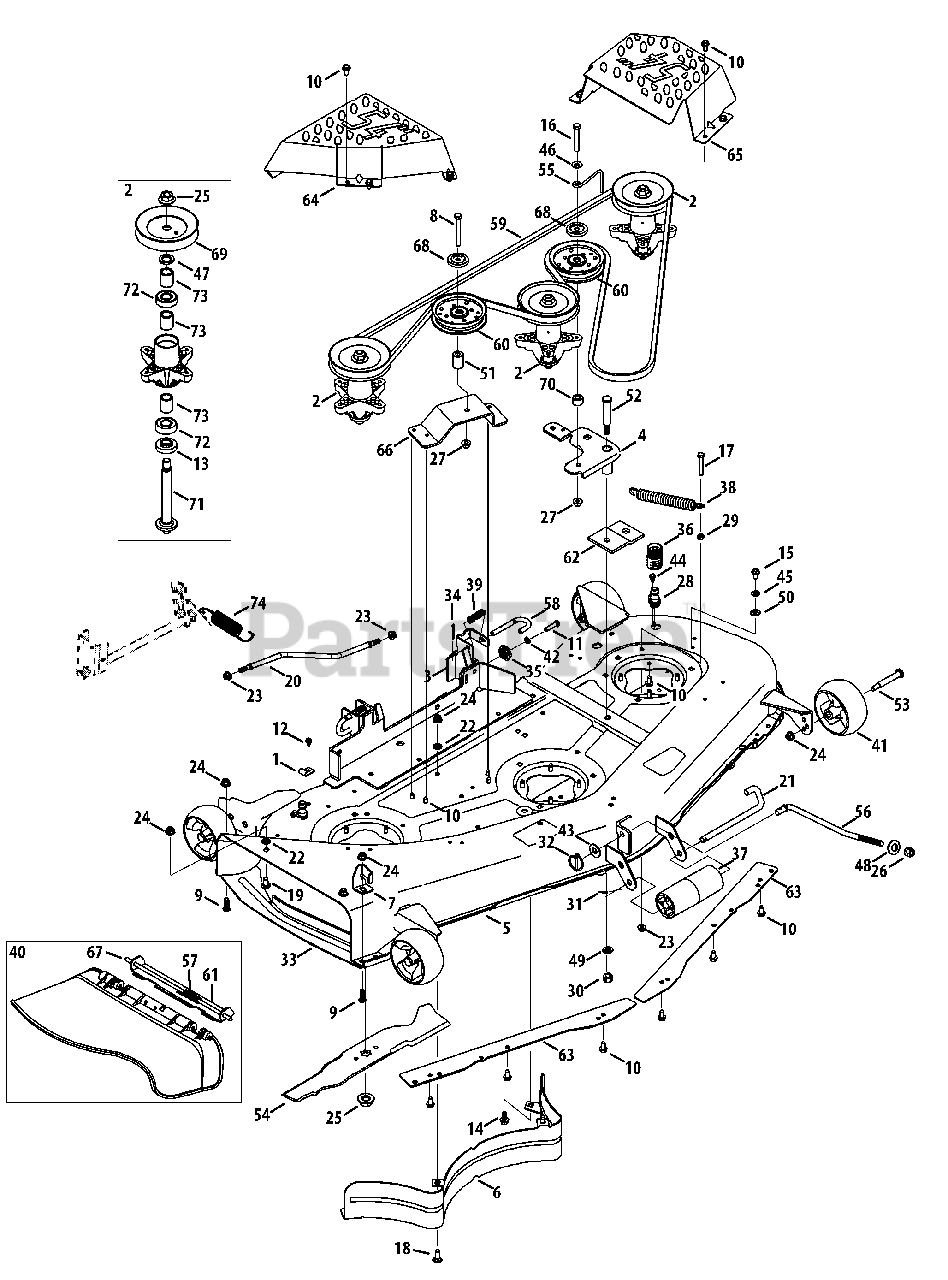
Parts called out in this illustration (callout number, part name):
1	Bracket, Hook, Retainer
2	Spindle Assembly
3	Bracket Assembly, Deck, Hanger LH
4	Idler Assembly, Arm, 54"
5	Deck Assembly, 54"
7	Stop, Chute, Deflector
8	Hex Screw, 3/8-16, 3.0, Gr8
9	Hex Screw, 3/8-16, 1.00, Gr5, Spec
10	Screw, Self-tapping, 5/16-18, .750,
11	Hex Screw, 5/16-18, 1.25, Gr5, Std
12	Screw, Self-tapping, 1/4-20, 0.500
13	Spacer, .79 x 1.82 x .55lg.
14	Screw, Self-tapping, 3/8-16, 0.750
15	Screw, Self-tapping, 5/16-18, 0.875
16	Hex Screw, 3/8-16, 2.50, Gr5, Std
17	Hex Screw, 5/16-18, 2.00, Gr5, Std
18	Bolt, Carriage, 3/8-16, 1.00, Gr5
19	Bolt, Carriage, 3/8-16, 0.75, Gr1
20	Rod, Support, Deck
21	Roller Pin-1/2 Dia. x 7.31
22	Nut, Push, 3/8
23	Nut, Flange Lock, 5/16-18, Nylon
24	Nut, Flange Lock, 3/8-16, Nylon
25	Nut, Flange, 5/8-18
26	Nut, 1/2-13
27	Nut, Flange Lock, 3/8-16, GrF
28	Deck Wash Nozzle
29	Nut, Hex, 5/16-18, Gr5
30	Nut, Hex Lock, 1/2-13, GrB
31	Pin, Cotter, 3/32, 1.0
32	Pin, Lynch, .1875
34	Pin, Cotter, 1/8 x 1.25
35	Gear, Deck, Adjustment
36	Coupler, Water
37	Roller, Front
38	Spring, Extension, .85 OD x 6.415
39	Spring, Compr’, .53 OD x 1.75
40	Chute Assembly
41	Wheel, Deck, 5.0 Dia. Ball
42	Washer, Lock, 5/16, Regular Duty
43	Washer, Flat, .531 x 1.25 x .100
44	Shoulder Screw, 1/4-20 x 0.50
45	Washer, Flat, .344 X .688 X .065
46	Washer, Flat, .406 x .875 x .059
47	Spacer, .790 x 1.25 x .175
48	Washer, Bell, .63 x 1.25 x .18
49	Washer, Lock, 1/2 , Regular Duty
50	Washer, Flat, .407x.812x.135
51	Spacer, .380 x .900 x 1.313
52	Bolt, Shoulder, .625 x 2.50, 1/2-13
53	Bolt, Shoulder, .496 x 2.50, 3/8-16
54	Blade, 18.50 Star 2 In 1
55	Rod, Keeper
56	Deck Lift Rod, Front, 11.7
57	Spring, Torsion, .44 I.D. x 2.0,
58	Rod, Deck Release
59	Belt, V-Type
60	Pulley, Idler, 4.25"Dia.
61	Bracket, Chute 50/54"
62	Bracket, Stabilizer, Pulley
63	Skirt, Deck, 54"
64	RH Spindle Cover
65	LH Spindle Cover
66	Bracket, Idler, Stationary
67	Pin, Hinge, .3175 Dia. x 14.06 ,1
68	Pulley Cap
69	Pulley, Deck, 5.39 Dia.
70	Spacer, .385 x .88 x .64
71	Spindle Shaft, 6.95 LG
72	Bearing, Ball, .787id x 1.85 Od x .551
73	Spacer, .80 x 1.10 x 1.322
74	Spring, Extension, 1.15 OD x 5.99
